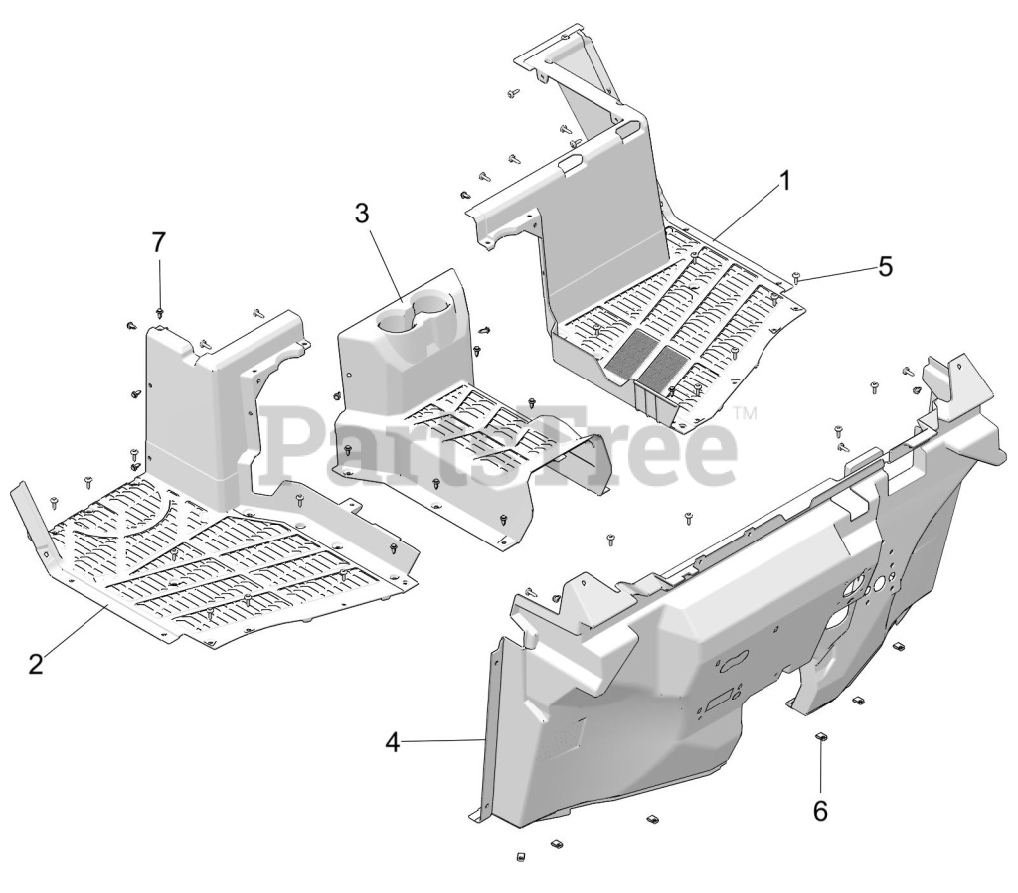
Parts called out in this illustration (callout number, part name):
1	FLOOR-LH-BLK
2	FLOOR-RH-BLK
3	COVER-TUNNEL FLOOR- BLK
4	FLOOR-UPPER CLOSEOFF,BLK
5	SCR-TXTH-M6X1.0X25 RIE
6	NUT-M6-1.0- U-TYPE (2.5-3.8)
7	RIVET-TUFLOK-.315-.325X.787 (5
